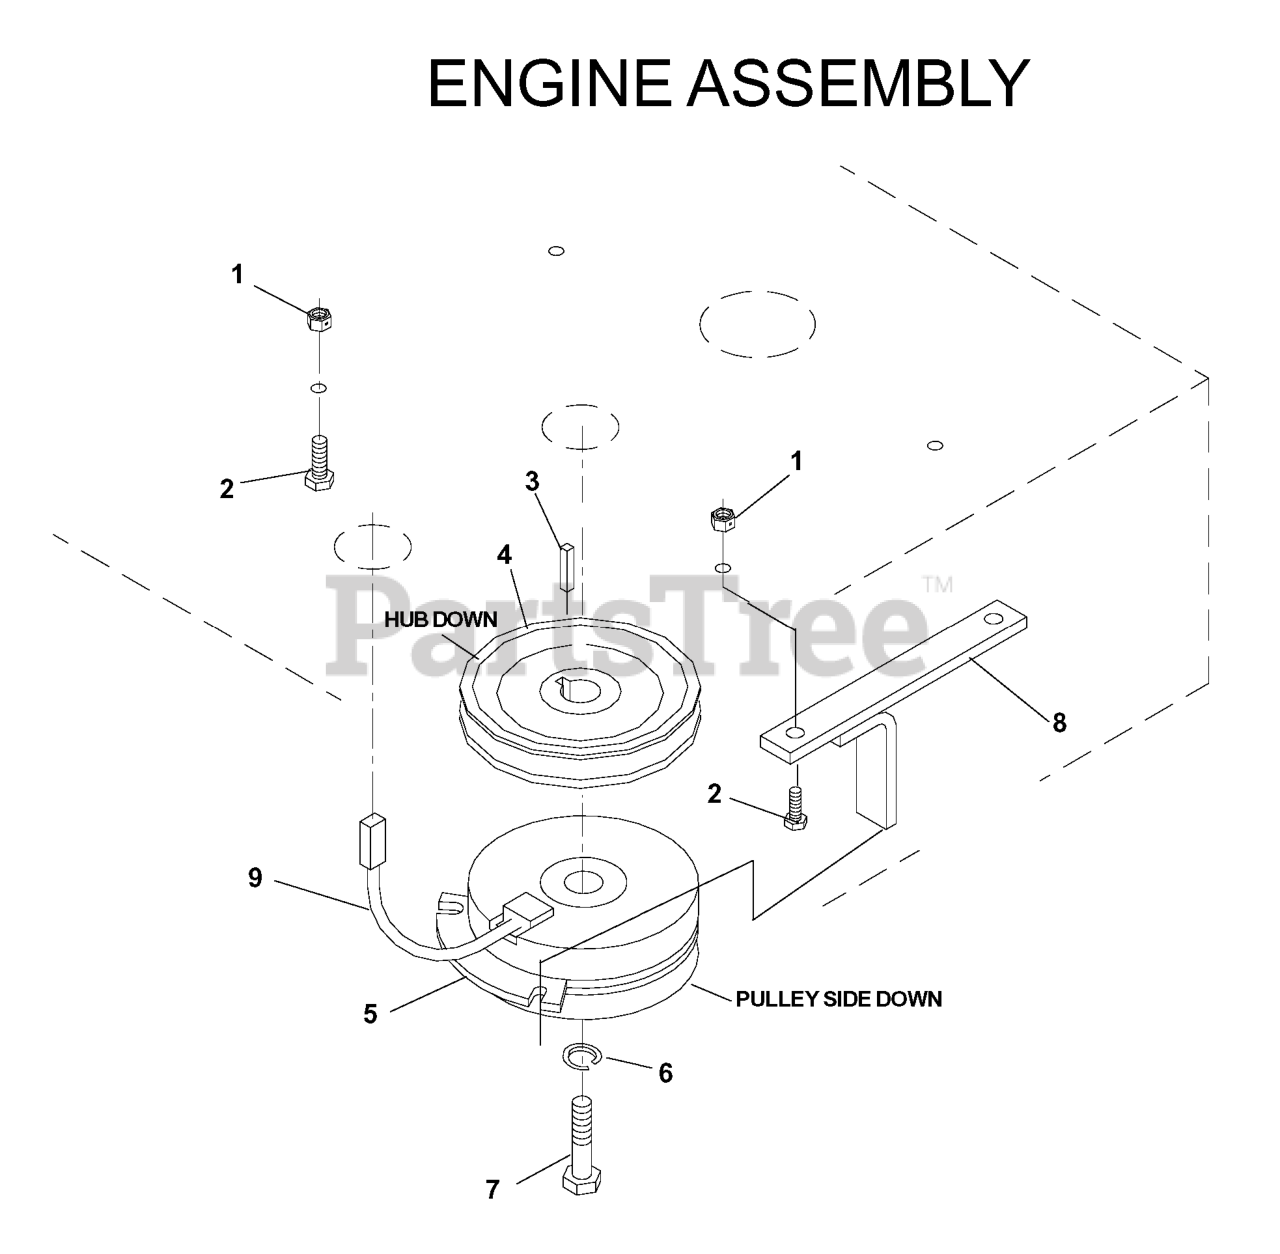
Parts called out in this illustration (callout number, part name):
1	NUT 5/16 NYLOC
2	HCS 5/16C X 1 3/4
3	KEY, 1/4 SQ X 1 1/4
5	CLUTCH-200 FT LB(RPLS 5218-102
6	WASHER 7/16 LOCK
7	BOLT 7/16F X 2 1/2
8	CLUTCH TIE DOWN
9	CLUTCH HARNESS
